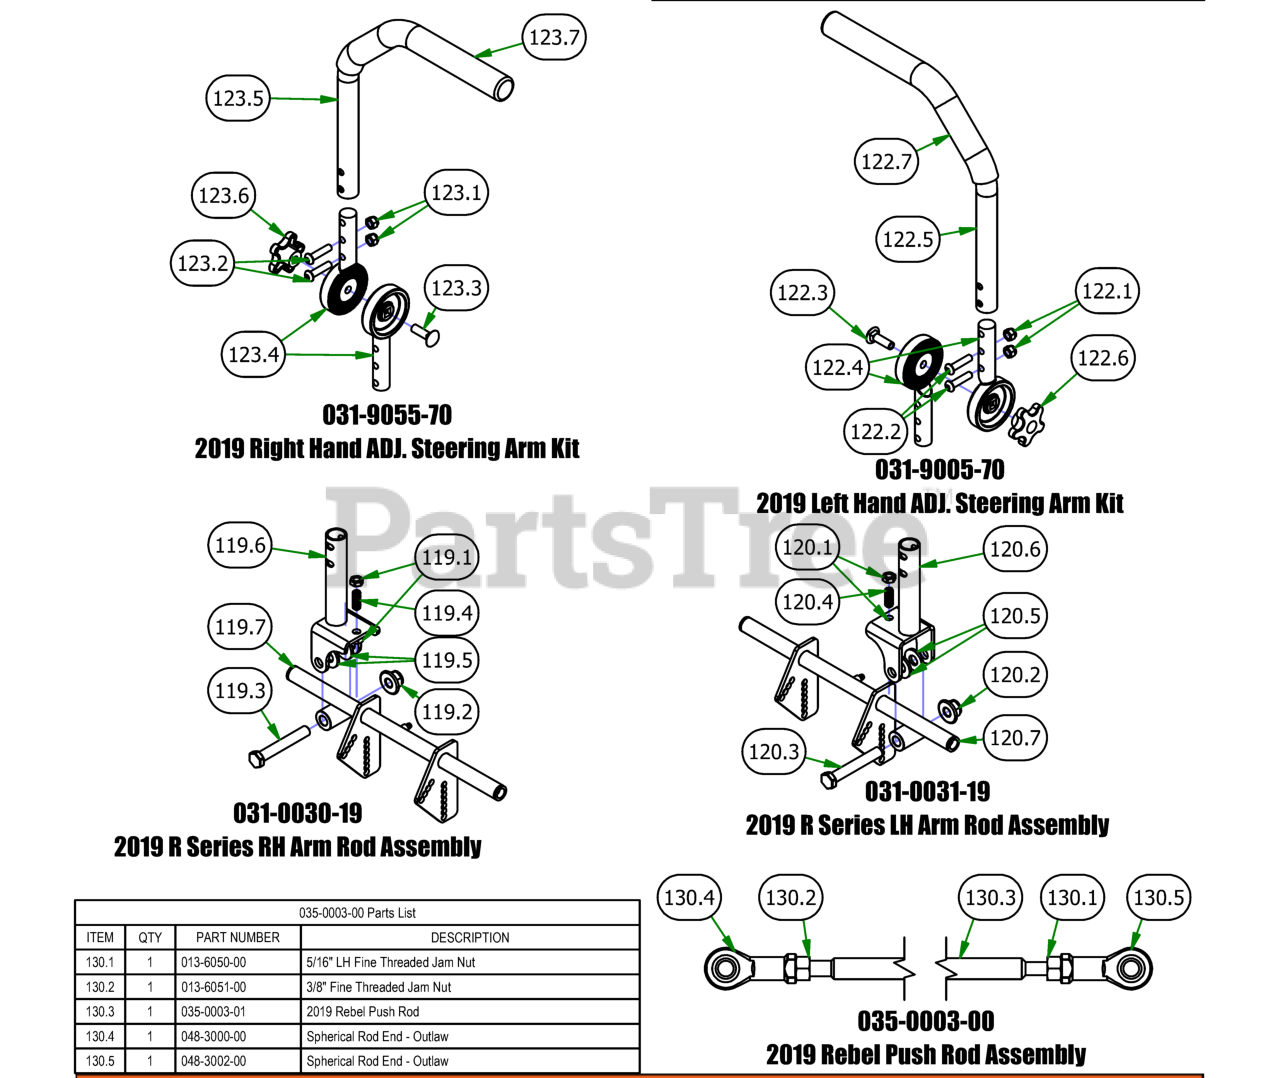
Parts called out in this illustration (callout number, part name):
119.1	3/8-16 Half Jam Nut
119.2	1/2-13 NYLON INSERT FLANGE LOCKNUT ZINC
119.3	1/2-13 x 3.25 GR 5 Hex Bolt Zinc
119.4	3/8-16 x 1 Set Socket Set Screw Cup Point
119.5	.505 Nylon Spacer
119.6	Drive Arm Pivot
119.7	2019 Drive Arm Actuator right
120.1	3/8-16 Half Jam Nut
120.2	1/2-13 NYLON INSERT FLANGE LOCKNUT ZINC
120.3	1/2-13 x 3.25 GR 5 Hex Bolt Zinc
120.4	3/8-16 x 1 Set Socket Set Screw Cup Point
120.5	.505 Nylon Spacer
120.6	Drive Arm Pivot
120.7	2019 Drive Arm Actuator left
122.1	5/16-18 Nylock Insert Locknut
122.2	5/16-18 UNC X 1-3/8" BHCS, TORX DRIVE, GR 5
122.3	3/8" x 1 1/4" Carriage Bolt
122.4	2019 Steering Arm Adjuster Casting
122.5	2019 Steering Arm Grip
122.6	Black Knob for Adjustable Steering Arm
122.7	Black Steering Arm Grip
123.1	5/16-18 Nylock Insert Locknut
123.2	5/16-18 UNC X 1-3/8" BHCS, TORX DRIVE, GR 5
123.3	3/8" x 1 1/4" Carriage Bolt
123.4	2019 Steering Arm Adjuster Casting
123.5	2019 Steering Arm Grip
123.6	Black Knob for Adjustable Steering Arm
123.7	Black Steering Arm Grip
130.1	5/16" LH Fine Threaded Jam Nut
130.2	3/8" Fine Threaded Jam Nut
130.3	2019 Rebel Push Rod
130.4	Spherical Rod End - Outlaw
130.5	Spherical Rod End - Outlaw
